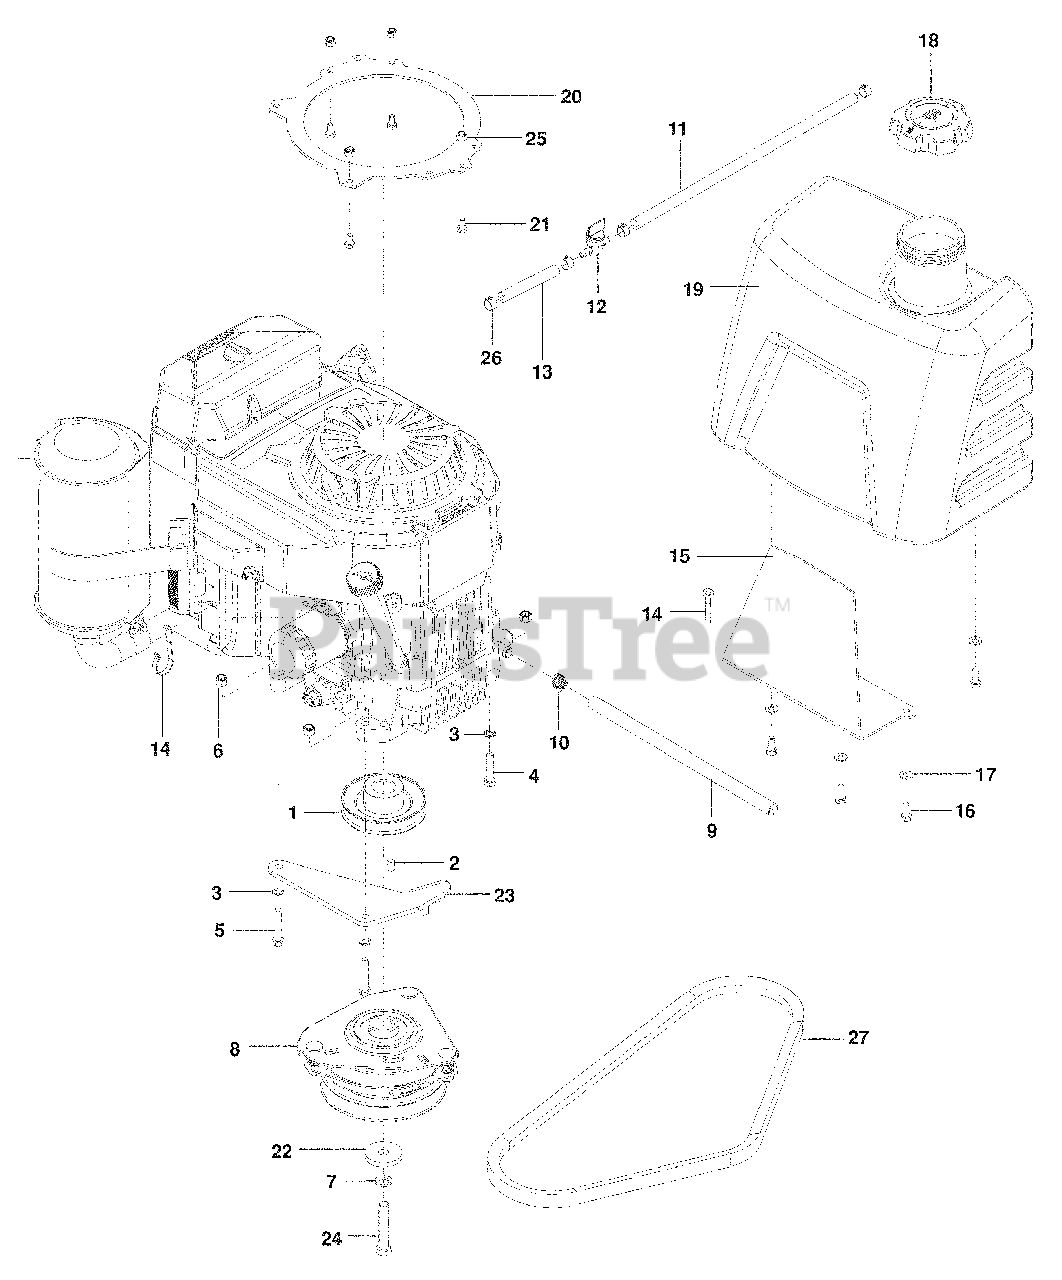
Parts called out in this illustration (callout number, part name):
2	KEY ¼ SQ x ½
3	LOCK WASHER 5/16 STAR
4	HCS 5/16-18 x 1½
5	HCS 5/16-18 x 1¾
6	NUT 5/16-18 HEX NYLOC
7	WASHER 7/16 SLW
8	CLUTCH 90 FT/LB
9	HOSE, OIL DRAIN
10	CLAMP, HOSE
11	FUEL LINE, 12"
12	VALVE, FUEL
13	FUEL LINE, 3½"
16	HCS 5/16-18 x ¾
17	WASHER 5/16 SAE FLAT
18	CAP, FUEL TANK
19	TANK, FUEL
20	ADAPTER, RECOIL
21	HCS ¼-20 x ½
22	WASHER, HEAVY
23	CLUTCH STOP
24	HCS 7/16-20 x 2½
25	NUT ¼-20 HEX NYLOC
